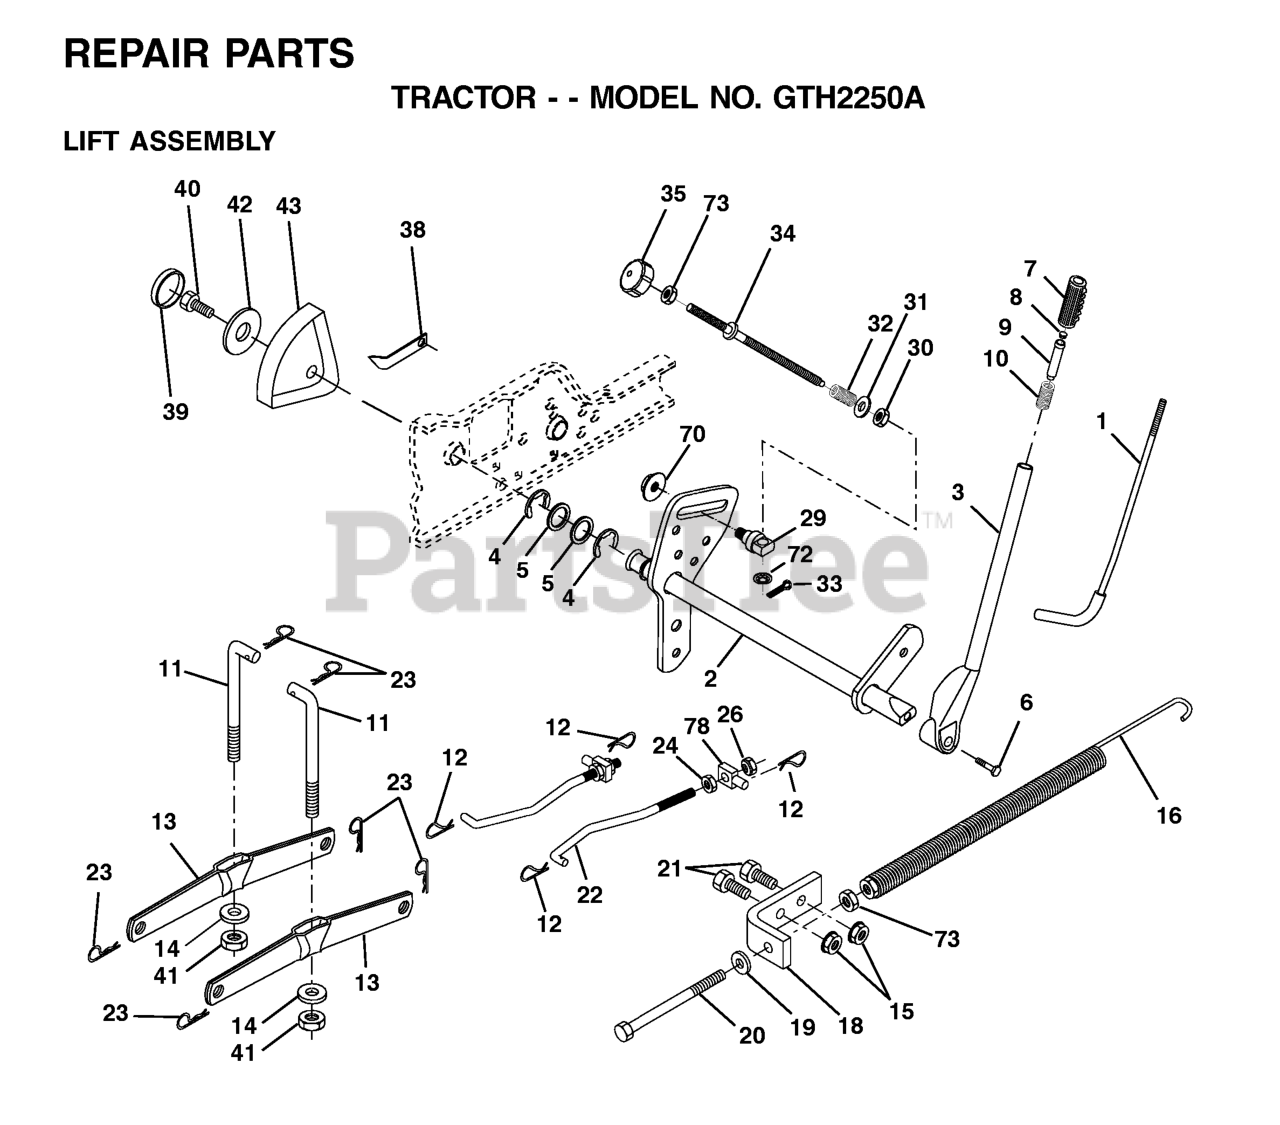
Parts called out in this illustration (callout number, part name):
1	LEVER ROD LT
3	LEVER ASSY-LIFT RH
5	Washer 29/32 x 1 - 1/4 x 16 Ga.
6	Bolt, Fin Hex 3/8-16 x 1-1/12
7	GRIP HANDLE
8	PLUNGER BUT KIT
9	PLUNGER BUT KIT
10	SPRING**
11	LINK LIFT
12	SPRING RETAINER
13	ARM.REAR.SUSPENSION
14	BEARING.PIVOT.LIFT
16	LIFT SPRING
19	WASHER
21	BOLT
22	FRONT LINK
23	RETAINER-SPRNG RB
24	NUT.HEX.JAM.1/2-13
26	NUT.LK.W/WSH.1/2.
32	SPRING.COMP.INF.H
33	COTTER PIN
34	ROD.LIFT.ADJUSTABLE
35	KNOB INF 3/8-16
38	POINTER, HEIGHT INDICATOR(2 2)
40	SCREW 5/16-18X1
41	NUT CROWNLOCK 3/8-24
43	HEIGHT INDICATOR
70	NUT
72	NUT PUSH M
73	NUT
78	TRUNION
